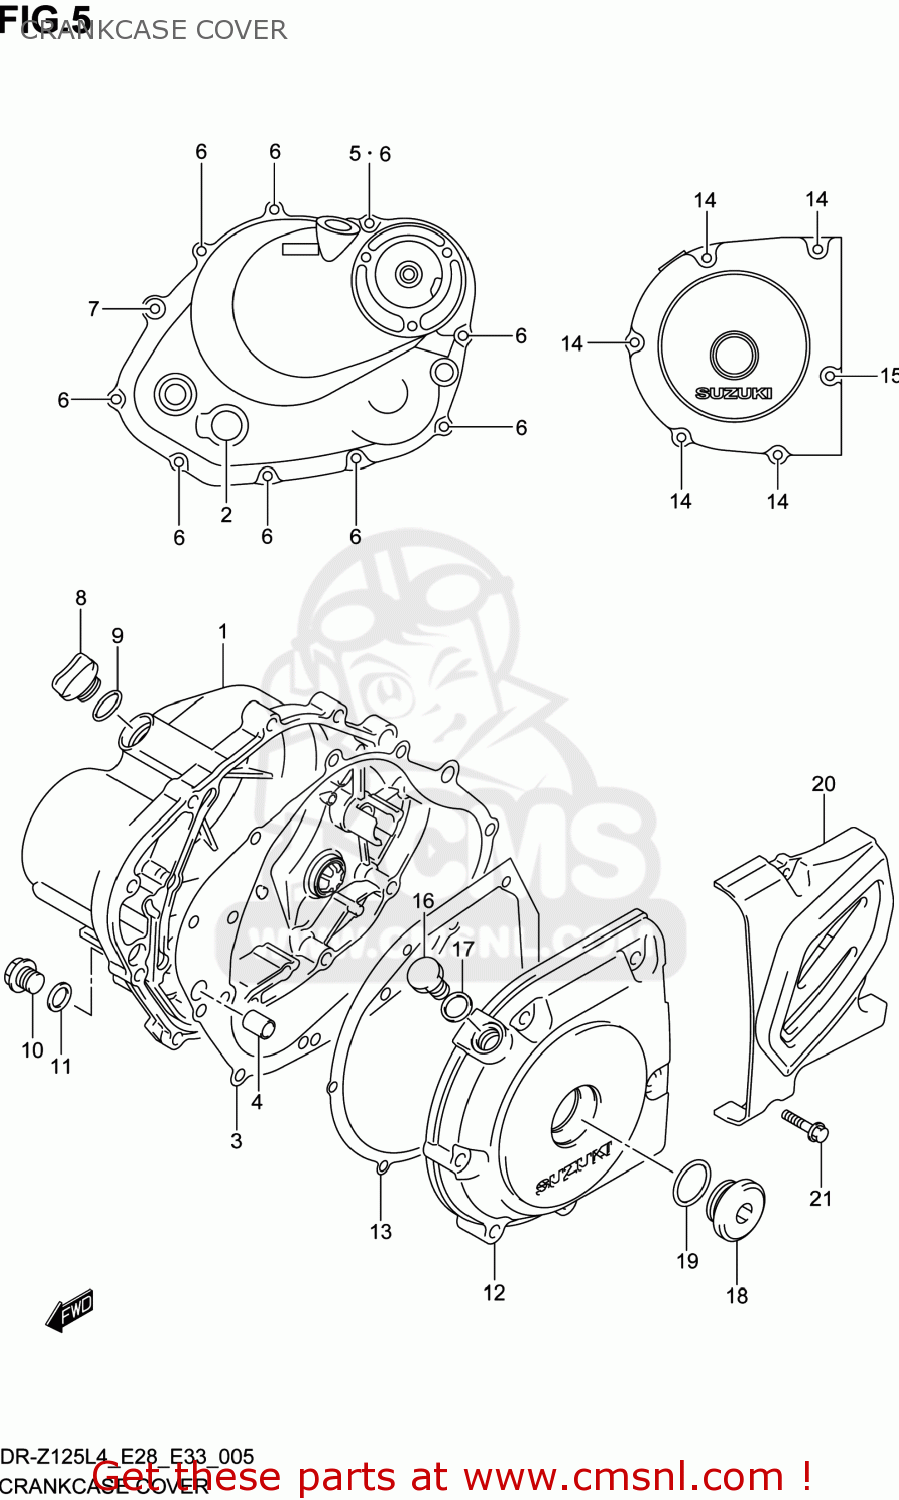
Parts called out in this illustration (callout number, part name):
1	COVER,CLUTCH
2	LENS,OIL LEVEL CHECK
3	GASKET,CLUTCH COVER (NAS)
4	PIN
5	GASKET(5.8X13X1.2) (NAS)
6	BOLT
7	BOLT
8	PLUG,ENGINE OIL FILLER
9	O RING(D:3.1,ID:16.8)
10	PLUG(14X12)
11	GASKET(13.8X18.8X4.8) (NAS)
12	COVER,MAGNETO
13	GASKET,MAGNETO COVER (NAS)
14	BOLT
15	BOLT
16	PLUG(12X9)
17	GASKET(12.1X16.2X3.7) (NAS)
18	PLUG(26X9)
19	O RING(D:3.1,ID:22.7)
20	COVER,ENGINE SPROCKET
21	BOLT
